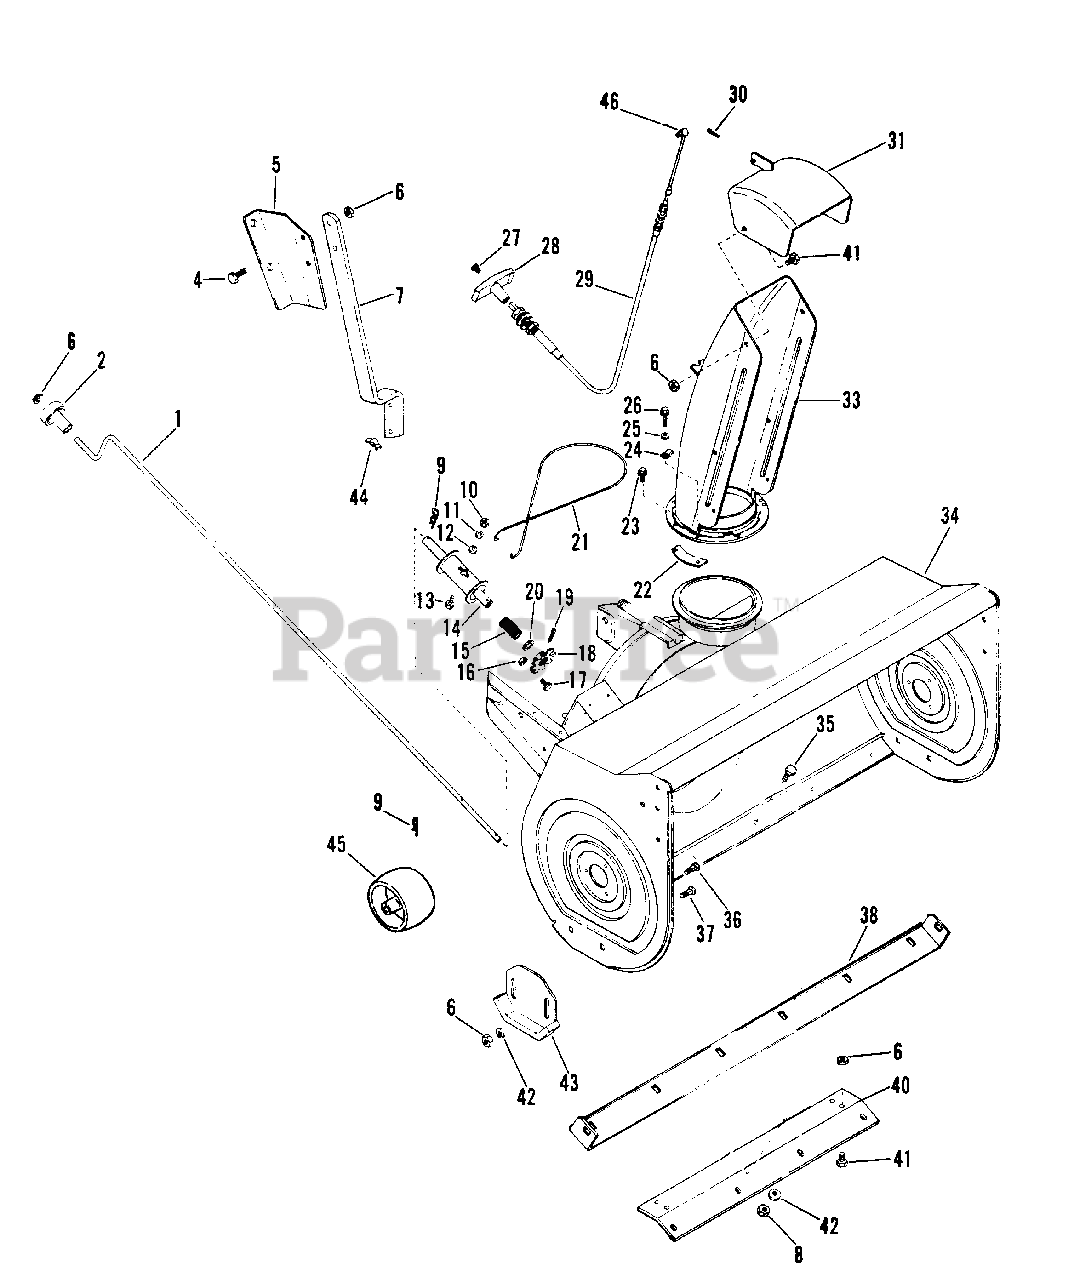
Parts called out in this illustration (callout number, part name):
1	Crank, Chute Control
2	Knob
4	Bolt, Hex 3/8-16x1.00
5	Bracket, Control
6	Nut, Lock 3/8-16
7	Support, Chute Crank
8	Nut, Lock 5/16-18
9	Hairpin, Internal
10	Nut, Hex 1/4-20
11	Washer, Lock 5/16 Reg.
12	Washer, Flat .281x.625x.065
13	Bolt, 1/4-20x.625 Rd Hd Sq Nk
14	Spool
15	Spring, Comp. 1.6 Free Length
16	Nut, Lock #10-24 Twin Whiz
17	Screw, #10-24x.375 Cap
18	Assembly, Disc.
19	Pin, Spring .187x1.00
20	Washer, Flat .640x1.005x.06
21	Cable
22	Clamp, Chute
23	Screw, Tapping 10-24x.50 HHD
24	Clamp, Cable
25	Washer, Flat .188x.375x.049
26	Taptite, #10-24x.75 PHD
27	Screw, Mach. 8-32x.75 PHD
28	Knob, Black
29	Cable, Control
30	Pin, Cotter .09x.75
31	Deflector, Chute
33	Chute, Discharge
34	Housing, 36" Snowblower
35	Bolt, Carriage 5/16-18x.75
36	Bolt, 3/8-16x1.00 Rd Hd Sq Nk
37	Bolt, 3/8-16x.75 Rd Hd Sq Nk
38	Blade, Scraper
40	Brace, Blade
41	Bolt, Hex 3/8-16x.75
42	Washer, Flat .406x.812x.065
43	Skid
44	Nut, Wing
45	Roller
